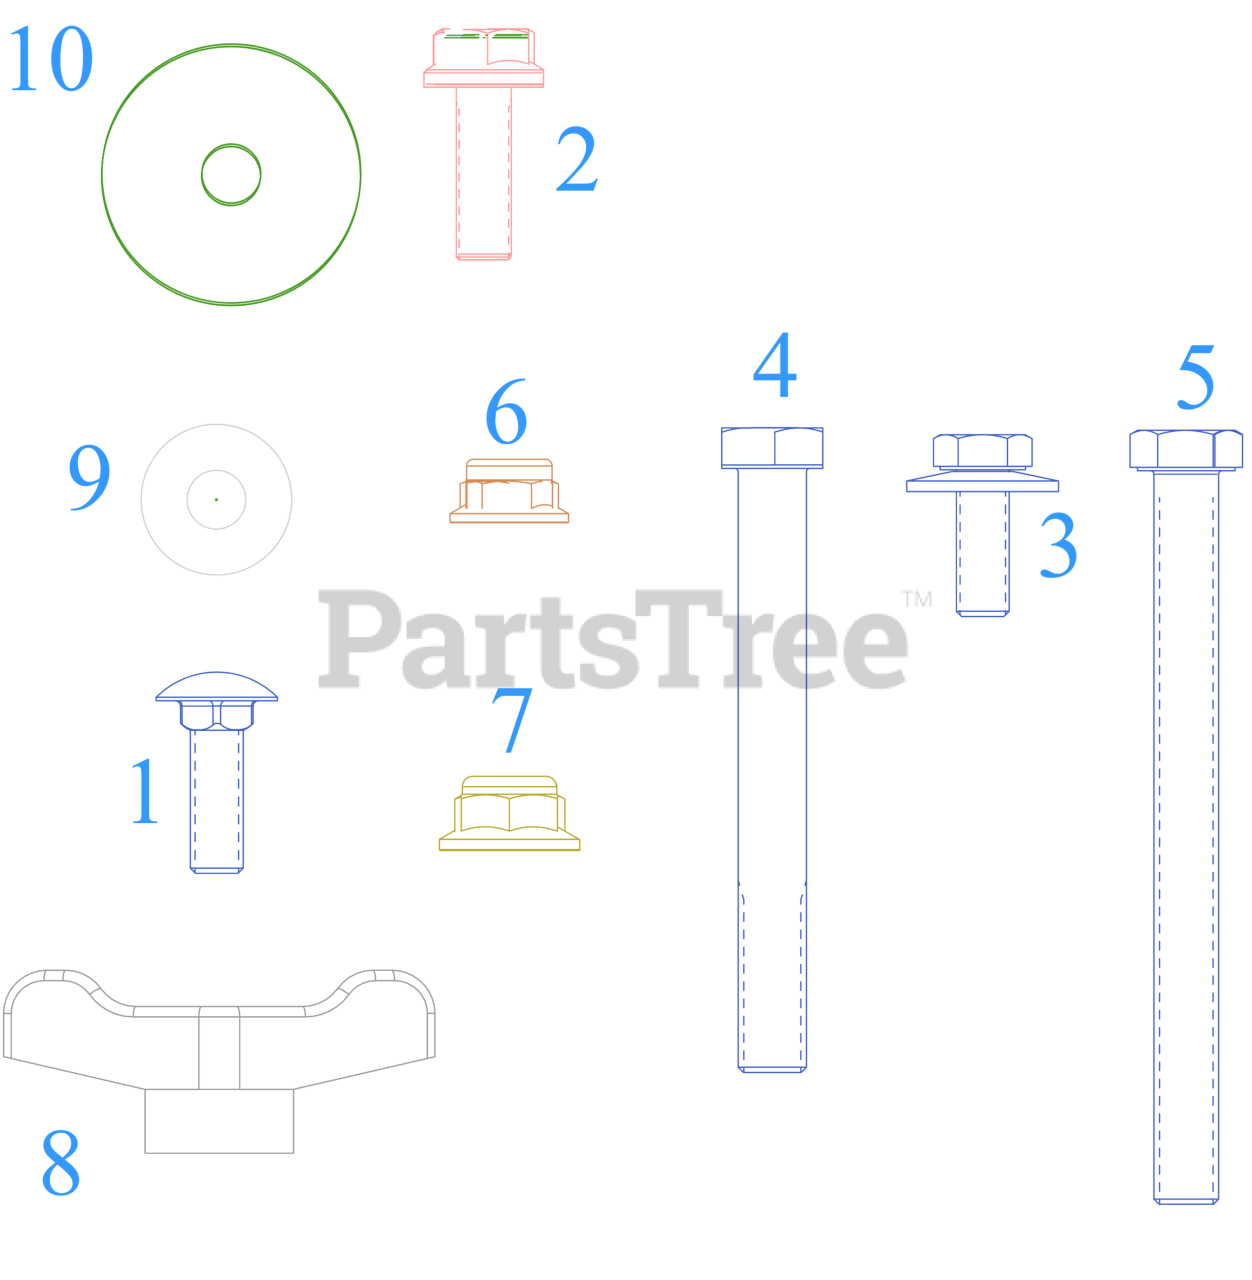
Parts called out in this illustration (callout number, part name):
1	CARRIAGE BOLT 5/16-18 x 1.00
2	SCREW 5/16-18 x 1 GR5
3	SCREW 5/16-24 x .85 GR5
4	SCREW 3/8-16 x 3.50 GR5
5	SCREW 3/8-16X4.25 GR5
6	FLANGE LOCK NUT 5/16-18
8	WING KNOB 5/16-18
9	BELL WASHER .337 X.867 x .057
10	FLAT WASHER
